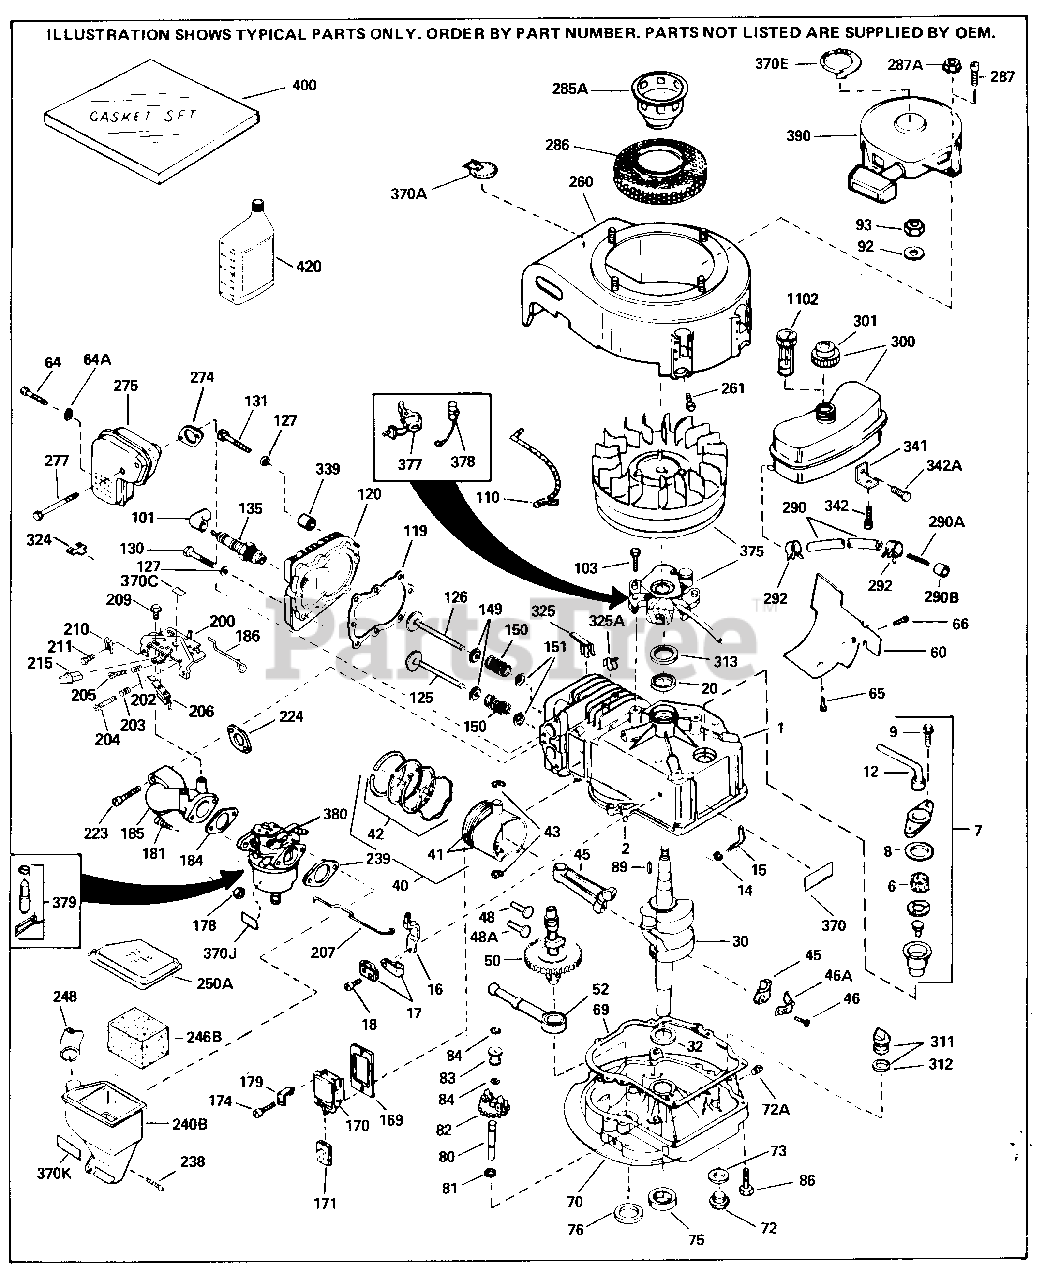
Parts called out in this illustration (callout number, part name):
1	"Cylinder (Incl. 2, 8, 9 & 20) 2-5/8" Bore
2	Dowel Pin
14	Flat Washer
15	Rod, Governor (Incl. 14)
16	Lever, Governor
17	Clamp, Governor lever Clamp is positi oned towardsspark plug end on 1977-78 and latermodels. It is positioned op posite spark plugend on earlier model s.
18	Screw, 8-32 x 5/16"
19	Spring, Governor
20	Seal, Oil
30	Crankshaft
32	Washer, Thrust
40	Piston, Pin & Ring Set (Std.) 2-5/8" Bore
40	Piston, Pin & Ring Set (.010" OS)
40	Piston, Pin & Ring Set (.020" OS)
41	Piston & Pin Ass'y. (Std.)(Incl. 43) 2-5/8"
41	Piston & Pin Ass'y. (.010" OS) Incl. 43
41	Piston & Pin Ass'y. (.020" OS) Incl. 43
42	Ring Set (Std.) (2-5/8" Bore)
42	Ring Set (.010" OS)
42	Ring Set (.020" OS)
43	Piston Pin Retaining Ring
45	Rod Assy., Connecting (Incl. 18)
46	Connecting Rod Bolt Early Production
46	Bolt, Connecting rod
46A	Plate, Lock Do not use with 32610A lo cking type screw
48	Valve Lifter
48A	Valve Lifter
50	Camshaft
52	Oil Pump Ass'y.
60	Blower Housing Extension
66	Screw, T-30, 1/4-20 x 1/2"
69	* Gasket, Mounting flange
70	Mounting Flange Ass'y. Incl. 72, 75 & 80
72	Plug, Oil drain (Incl. 73)
72A	Oil Drain Plug (Use as required)
73	* Drain Plug Gasket Do not use w/plast ic plug
75	Oil Seal
80	Shaft, Mechanical governor
81	Washer, Flat
82	Gear Assy., Governor (Incl. 81)
83	Spool, Governor
84	Retaining Ring
86	Screw, 1/4-20 x 1-1/4"
89	Key, Flywheel
92	Washer, Belleville
93	Nut, Flywheel
103	Screw, 1/4-20 x 5/8"
110	Ground Wire
119	* Gasket, Cylinder head
120	Head, Cylinder (Incl. 131)
125	Intake Valve (STD)(Incl. 151) Inverte d Ports
125	Intake Valve (1/32" OS) (Incl. 151) ( Inverted Ports)
126	Exhaust Valve (Std.) (Incl. 151) (Inv erted Ports)
126	Exhaust Valve (1/32" OS) (Incl. 151) (Inverted Ports)
127	Washer (Used on late production)
130	Screw, 5/16-18 x 1-1/2" Use as requir ed
131	Screw, 5/16-18 x 2" (Use as required)
131	Screw, 5/16-18 x 2-1/2" Use as requir ed
135	Resistor Spark Plug - RJ17LM
149	Valve Spring Cap) Used in early produ ction
150	Spring, Valve
151	Cap, Lower valve spring
169	* Gasket, Valve spring cover
170	Body Assy., Breather Incl. 169 & 171
171	Element, Breather
174	Screw, 10-24 x 1/2"
178	Nut & Lock Washer 1/4-28
181	Screw, 1/4-28 x 7/8"
182	Screw, 1/4-28 x 7/8"
184	* Gasket, Carburetor
185	Pipe, Intake
186	Link, Governor spring
200	Control Bracket Incl. 203, 204 & 206
203	Spring, Compression
204	Screw, 5-40 x 7/16"
206	Terminal Assy.
207	Link, Governor-to-throttle
209	Screw, 10-24 x 9/16"
223	Screw, 1/4-20 x 13/16"
224	* Gasket, Intake
238	Screw, 10-32 x 7/16"
239	* Gasket, Air cleaner
260	Housing, Blower NOTE: Replacement har dware may differ when servicing start er assy. or blower housing. Refer to Service Bulletin 508.
261	Screw, 1/4 20 x 5/8"
274	* Gasket, Exhaust
275	Muffler (Incl. 274)
277	Screw, T-30, 1/4-20 x 1/2" as req.)
287	Pop Rivet (Purchase locally) 3/16" di a.
287	Screw, 1/4-28 x 7/16" Use as require d
287	Screw & Lockwasher, 1/4-28 x 1/2"
287A	Nut & Lock Washer 1/4-28 ired)
290	Fuel Line (8.62") as req.)
290	Fuel Line (Braided 16")(40 cm) Use as req.
290	Fuel Line (Epichlorohydrin 6-3/4") 1 7 cm
290A	Fuel Line (Metal 3-3/8")
290B	Fuel Line (8.62") (21cm)
292	Fuel Line Clamp
300	Fuel Tank (Incl. 301)
301	Fuel Cap (Red 1-1/2" ID) also availab le in Packaged Part #740005B
301	Fuel Cap (use as required)
301	Fuel Cap (Std.) (Use as required)
325A	Wire Clip
370	Decal, Instruction
375	Magneto (W/Ring Gear) NOTE: This mag neto is not available as an assembly. The magneto number is shown for ref erence purposes only. Order componen t parts individually, as shown in par ts breakdown. Refer to Division 5, Se ction B, page24 or Fiche
377	Breaker Points (also available in Pac kaged Part #740037B)
378	Condenser (also available in Packaged Part #740037B)
379	Inlet Needle, Seat, Gasket & Spring A ssy.
400	* Gasket Set (Incl. items marked *)
420	SAE 30 4-Cycle Engine Oil (Quart)
1102	Gauge, Visual fuel
